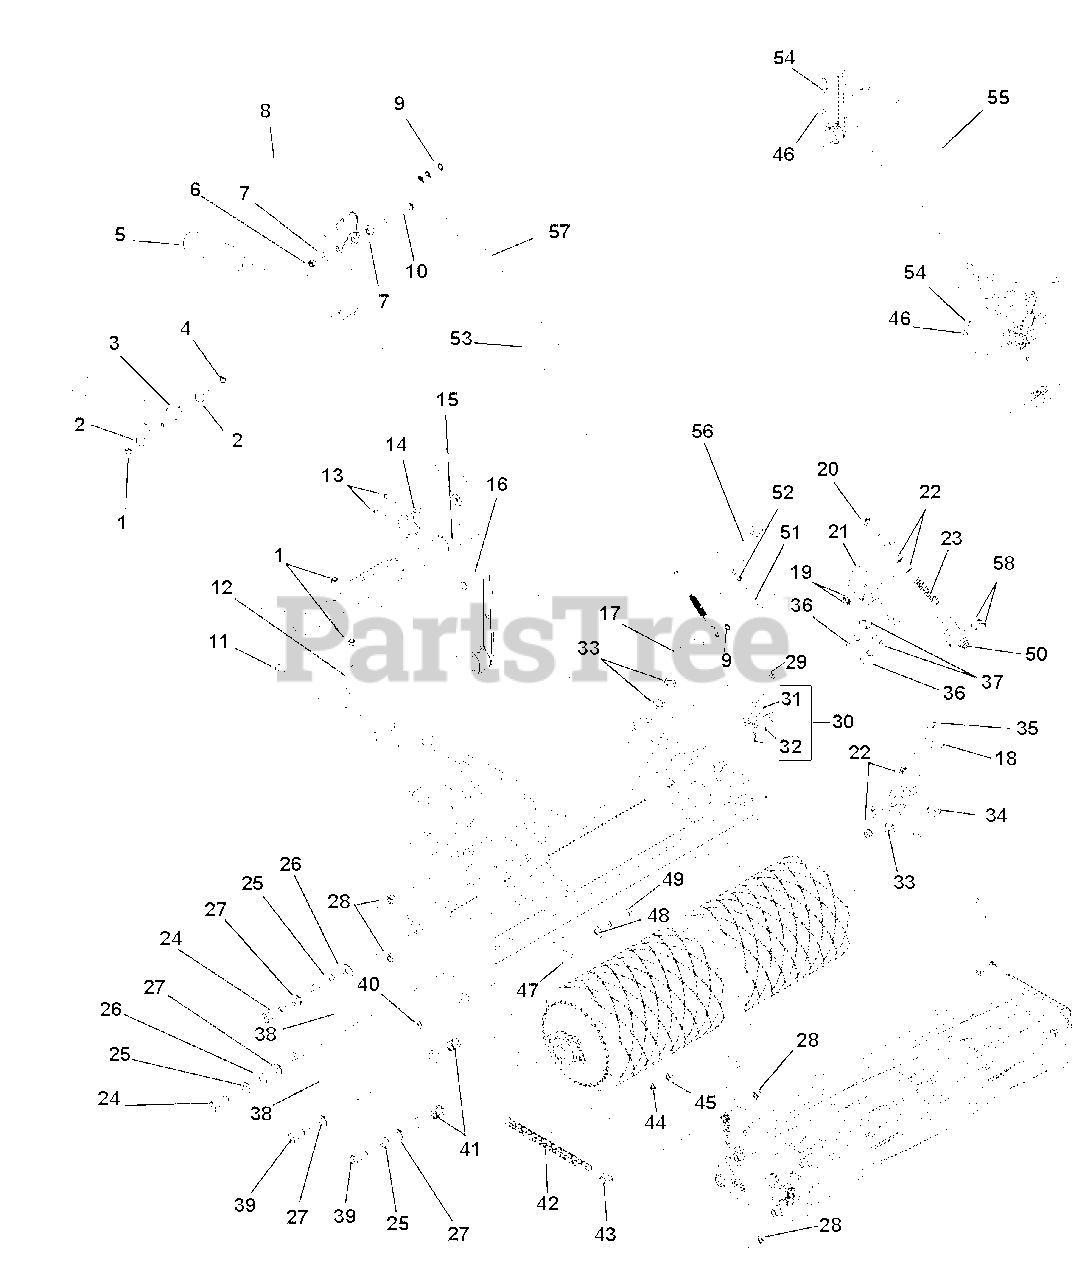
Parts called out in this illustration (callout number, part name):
1	Nut, Hex .25-20
2	Washer, Flat .25
3	Stop, Handle
4	Screw, Pan Head Slotted .25-20 x 2
6	Nut, Hex .25-20 Nyloc
7	Bushing, Flange
8	Paddle, Right Hand
9	Ring, Retaining .25
10	Cap Screw, Hex Head .25-20 x 2.5
11	Screw, Caster Pin .25-28 Pan Head Slotted Stainless Steel
12	Eyebolt .25-20 x 1.563
13	Screw, Round Head Machine 10-24 x .75
14	Cap, Hand Lever
15	Bushing, Lever
16	Handle, Reel Lift
17	Braking Block, Left Side
18	Cap Screw, Hex Head .50-20 x 3.5
19	Nut, Nylock #10-24
20	Bolt, Carriage .312-18 x 1.5
21	Braking Retainer, Left Hand
22	Nut, Hex .312-18
24	Screw, Shoulder .50 Diameter .38 x 1
25	Washer, Metal Bushing .50 x 18
27	Bushing, Sintered Steel, Oil Impregnated
28	Nut, Hex .375-16
30	Assembly, Brake (Includes Items 31 & 32)
31	Shoe, Brake
32	Pad, Brake
33	Nut, Hex Jam .50-20
34	Lever, Clutch Fork
35	Cap Screw, Hex Head .312-18 x 1.5
36	Cap Screw, Hex Head .50-20 x 1
37	Washer, Lock .50
38	Arm, Reel
39	Bolt, Arm Stainless Steel, .50 Shoulder 18-8
40	Cap Screw, Flat Head Socket .312-18 x 1 Stainless Steel
41	Spring, Reel .750 OD x .090 Wire Diameter x .730 – .750 Free Length
42	Chain, Traction Drive (31" #423)
43	Master Link
44	Washer, Lock .312
45	Nut, Hex .312-10
46	Washer, Flat .312
47	Adjuster, Chain
48	Washer, Flat .375
49	Cap Screw, Hex Head .38-16 x 1.75
50	Switch, Double Pole Plunger
51	Eyebolt .186 10-24 x 3
52	Nut, Hex 10-24
53	Cable Assembly, CL Brake
54	Pin, Cotter
55	Rod, Mower Lift 29-Inch
56	Cap Screw, Hex Head .50-20 x 3
57	Cable Assembly, CL Reel Clutch
58	Screw, Pan Head Phillips 10-20 x .75
